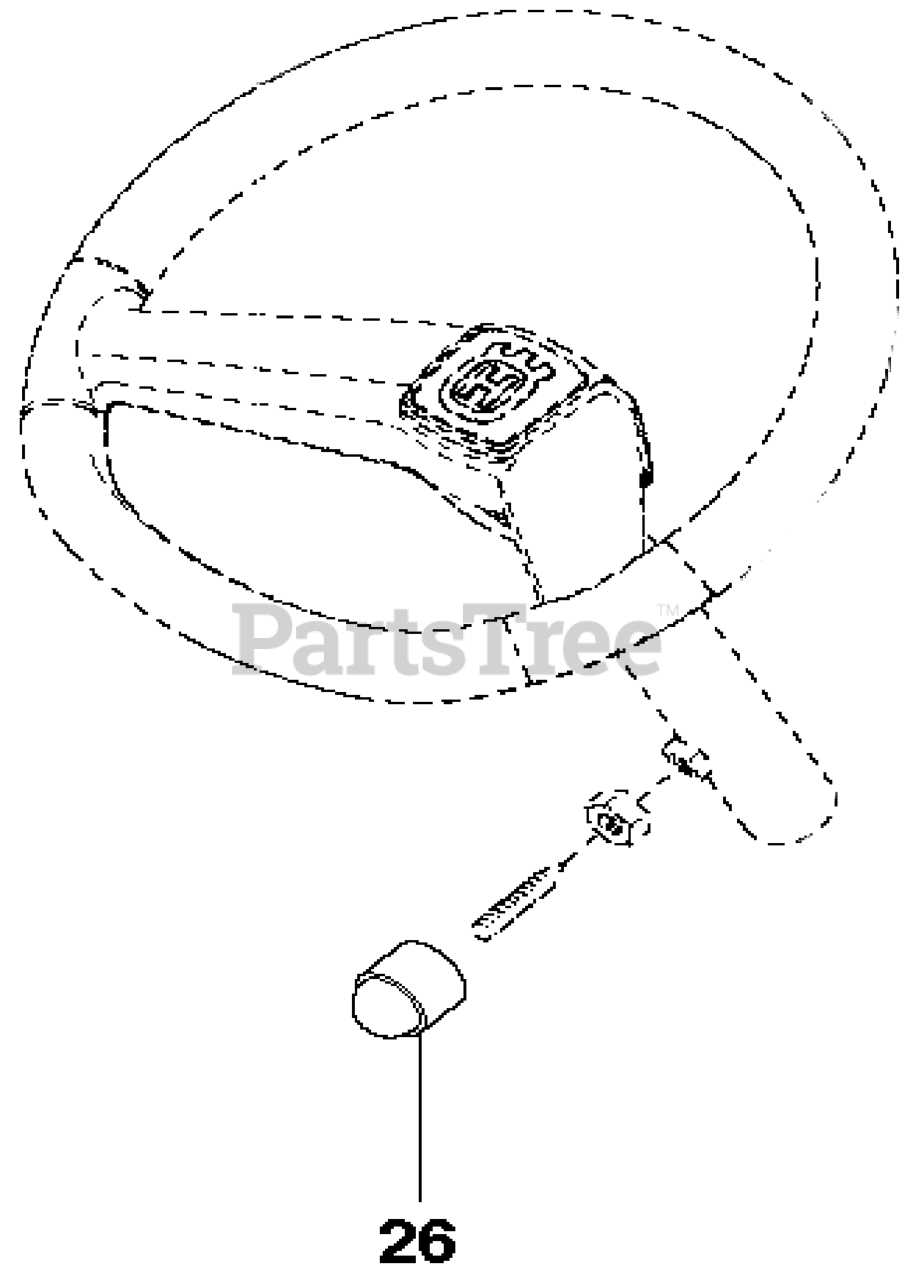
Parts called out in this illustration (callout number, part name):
3	FOOT PLATE
4	FOOT PLATE
9	CONTROL COVER
10	LOCKING NUT
12	MAT COVER FRAME
26	PROTECTIVE COVER
